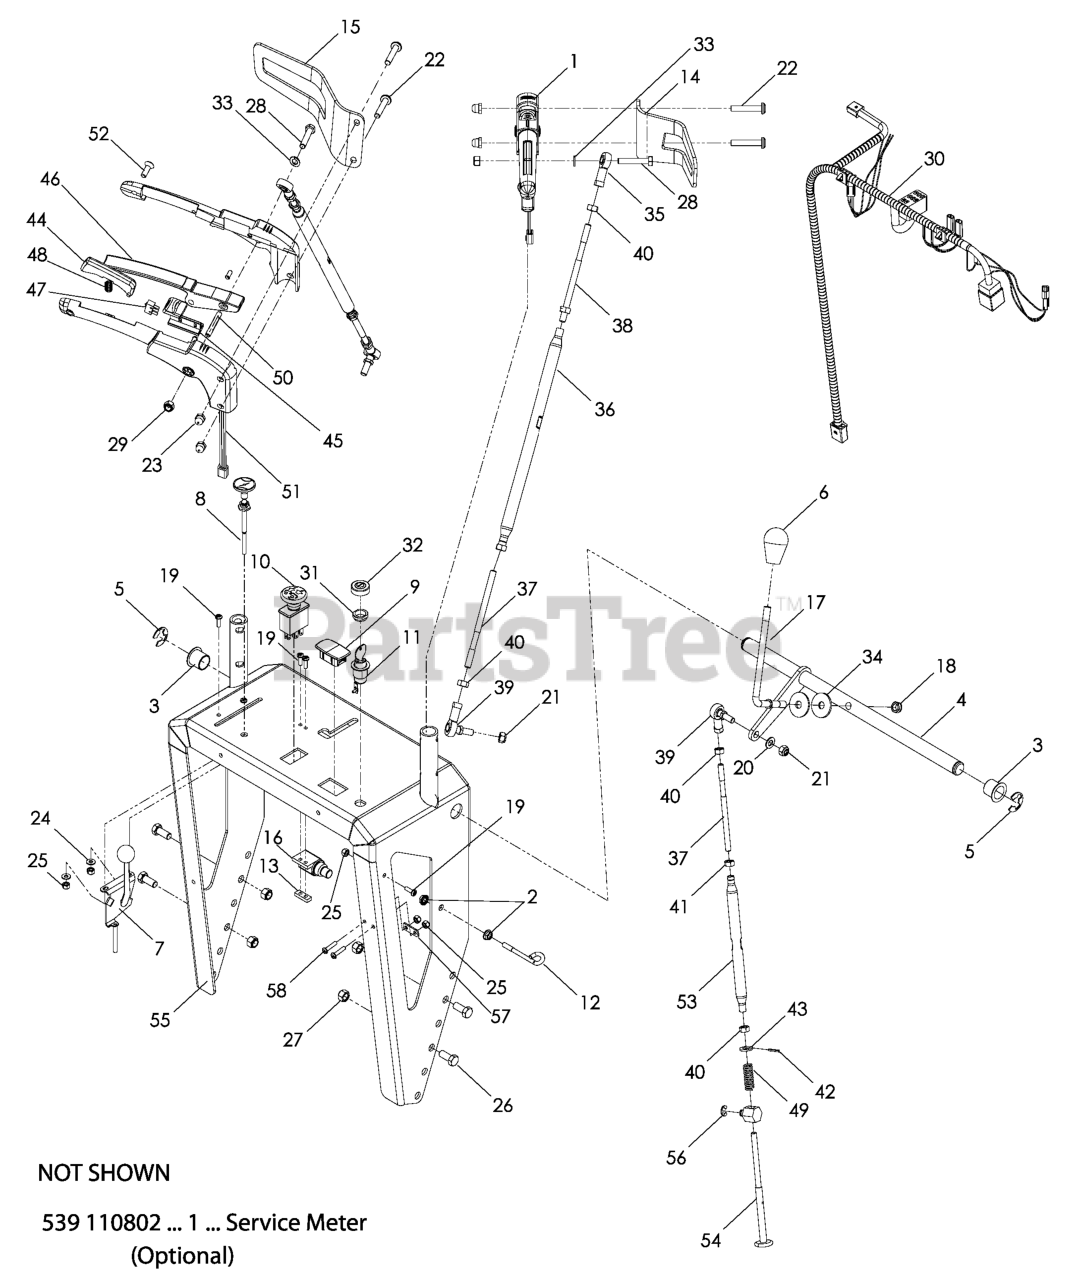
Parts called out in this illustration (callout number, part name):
2	NUT 5/16C WHIZ
3	BEARING - FLANGE, 20MM
4	SPEED CONTROL
5	E-RING, 20MM
6	KNOB - SHIFT
7	THROTTLE CONTROL
8	CONTROL-CHOKE 51"
9	PLUG DASH
10	RP.SWITCH, BLADE
11	KEY SWITCH, COMPLETE
12	GUIDE - ROPE
13	TAPPED PLATE
14	GUARD, HAND - OFFSET RH, PTD
15	GUARD, HAND - OFFSET LH, PTD
16	SWITCH, NC PLUNGER
17	ROD-SHIFT R/B 522676001
18	NUT HEX 3/8-16 NYLON, THIN
19	HCS #10-24 X 1/2
20	FLAT WASHER 5/16 SAE
21	NUT M8-1.25 TOP NYL GR10 ZD
22	SCR. PAN HD - 5/16-18 X 1.75 L
23	NUT ACORN 5/16-18
24	WASHER #10
25	NUT 10-24 NYLOC
26	HCS 3/8-16 X 7/8 GR 5 ZD
27	NUT 3/8-16 NYLOC
28	HCS 5/16C X 1 3/4
29	NUT 5/16 NYLOC
30	HARNESS, UPPER HANDLE
31	DNO IGNITION NUT
32	CAP IGNITION NUT
33	WASHER.LOCK.HVY.HLCL.SPR.5/16
34	CONE WASHER
35	ROD END 8 MM, RH
36	TUBE - ADJUSTING
39	ROD END 8 MM, W/STUD
40	NUT 8MM X 1.25 HEX ZD
41	NUT, 8MM X 1.25 LEFT HAND
42	ROLL PIN - 3 MM
43	WASHER, 10MM
44	OPC ACTUATOR
45	LOCK - NEUTRAL
50	PIN - GROOVE 1/4 X 1-1/2
51	HARNESS - SWITCH
52	SCREW - OVAL HEAD 6MM
53	TUBE - ADJUSTING
54	ROD - HEADED
55	HANDLE W/DECAL
56	E-RING, 10MM
57	MODULE
58	SCREW, #1--24 X 1/2 SLOTTED
